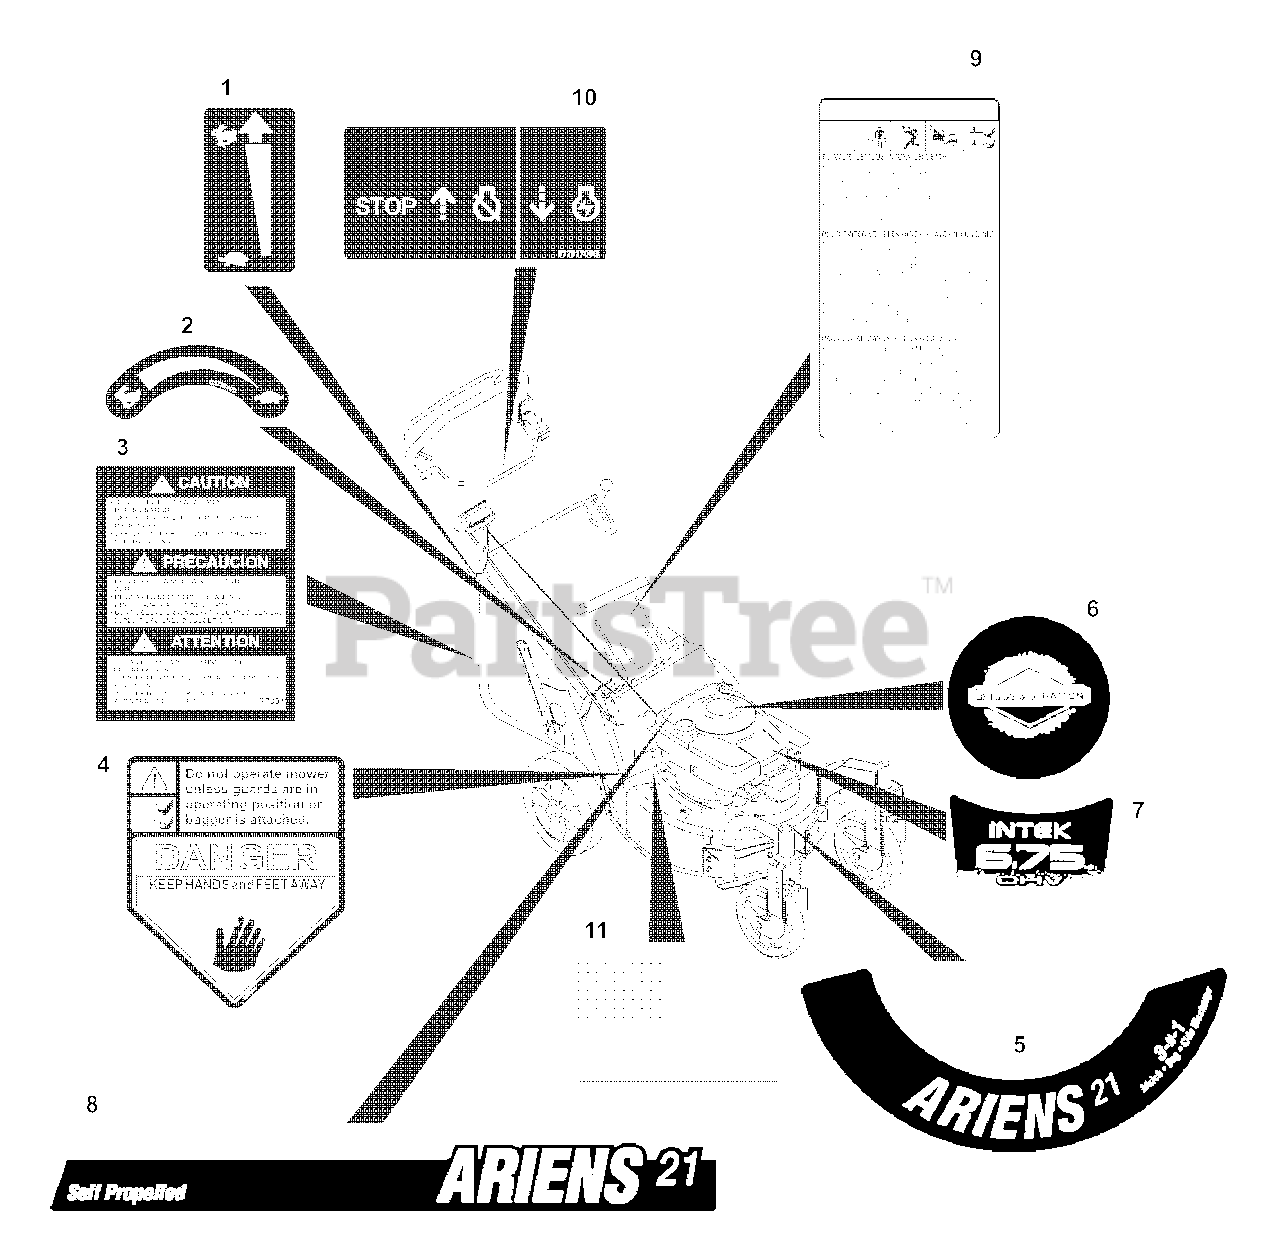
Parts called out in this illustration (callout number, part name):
1	DECAL-SPEED CONTROL
2	DECAL, TURTLE & RABBIT
3	LABEL - BAGGER 21"
4	DECAL, CPSC DANGER
5	DECAL, ARIENS DECK
6	DECAL,BRIGGS & STRATTON RECOIL
7	DECAL, B&S INTEK 6.75HP
8	DECAL, DRIVE COVER SP
9	DECAL, BILINGUAL DANGER
10	DECAL - ENGINE CONTROL
11	DECAL, AMERICAN FLAG
